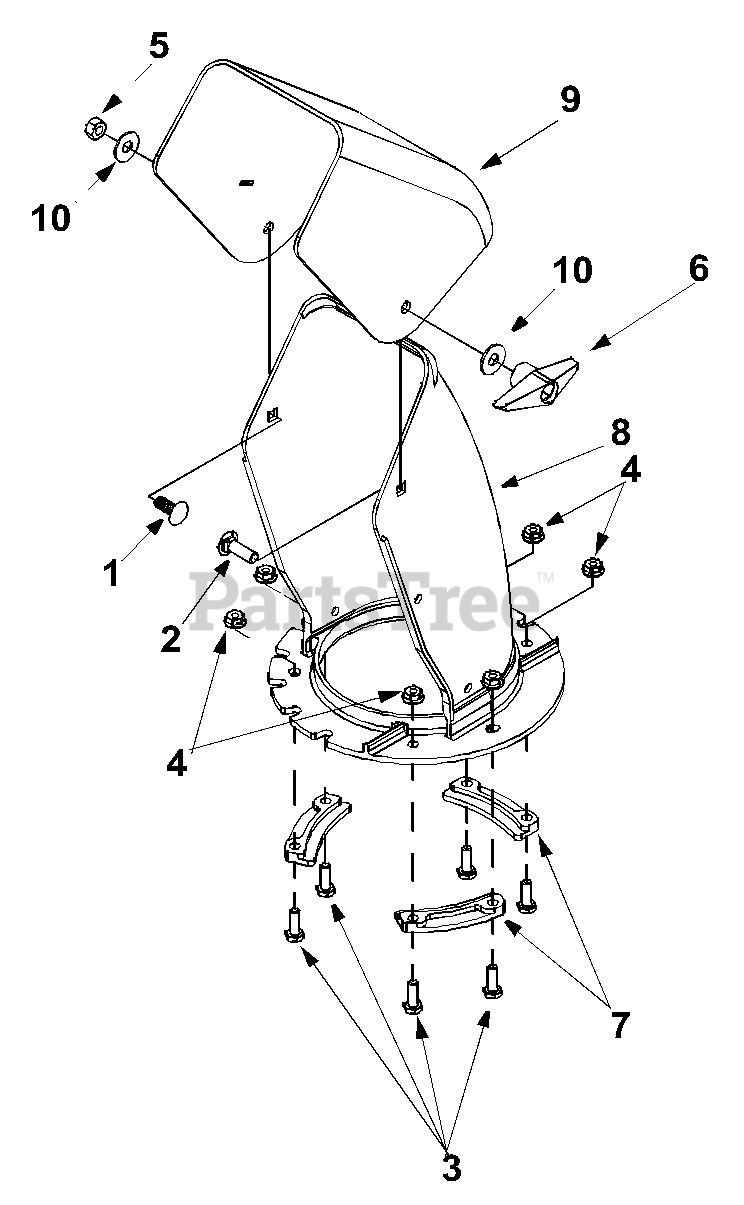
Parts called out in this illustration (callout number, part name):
1	Carriage Screw: Special
2	Carr. Bolt 5/16-18 x 0.750"
3	Hex Screw 1/4-20 x 0.75"
4	Lock Nut
5	Hex Lock Nut
6	Hand Knob
7	Flange Keeper: Chute
8	Lower Chute
9	Upper Chute
10	Washer
